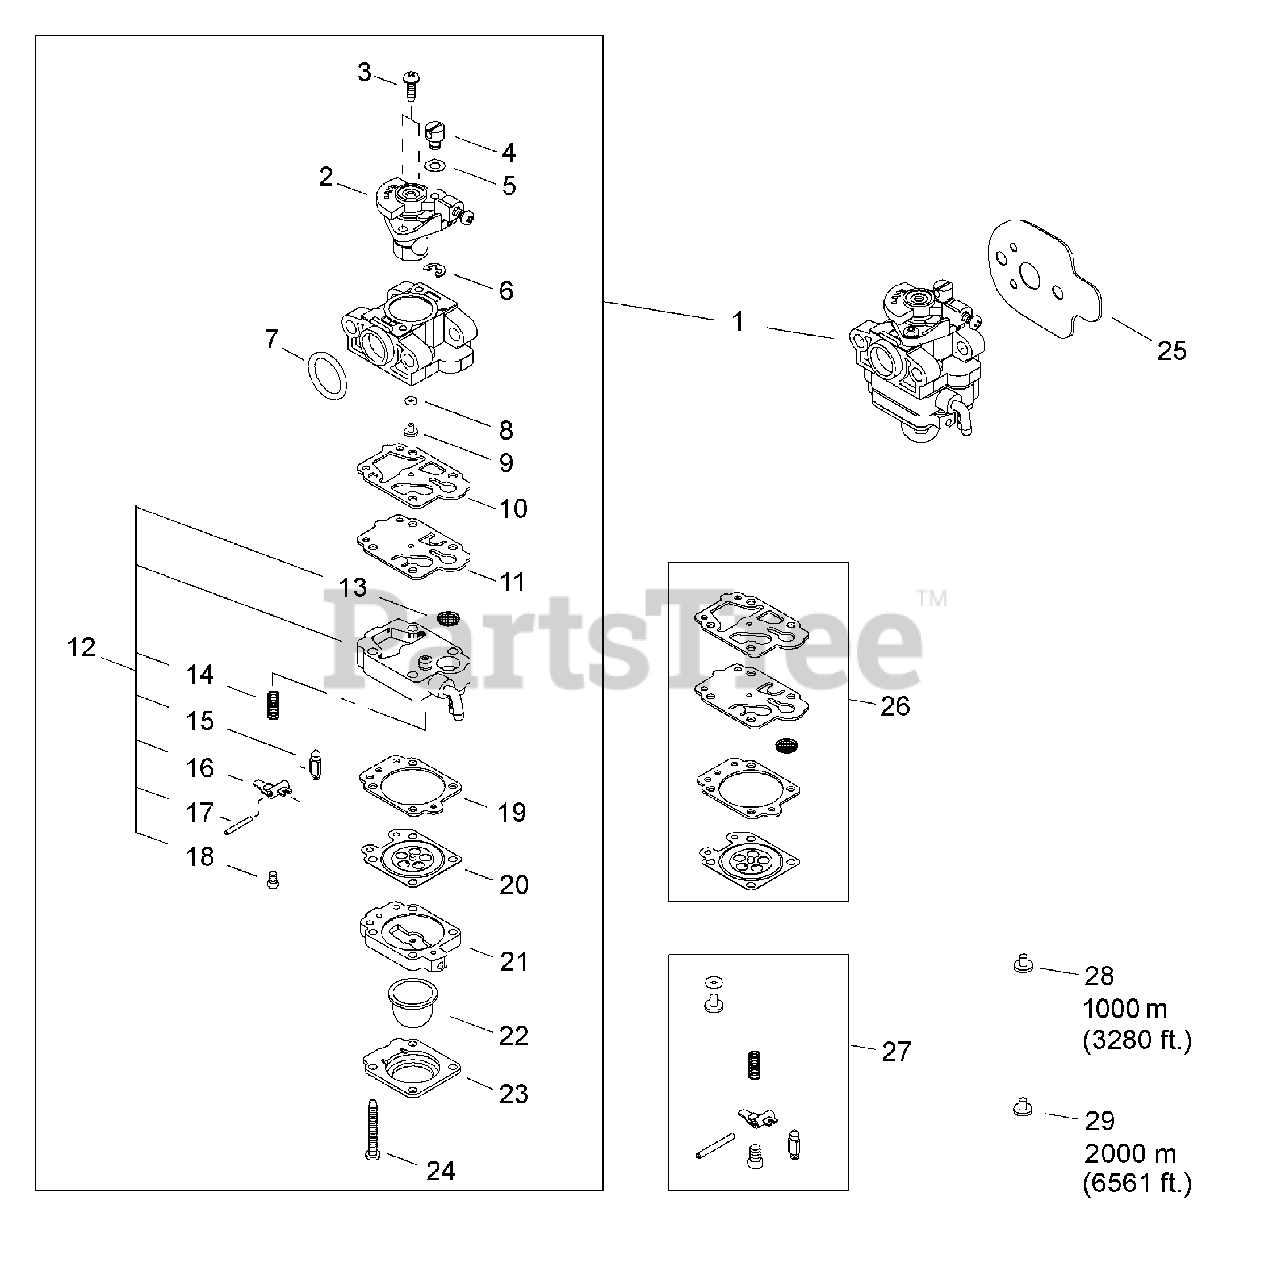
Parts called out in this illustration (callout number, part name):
1	CARBURETOR
2	THROTTLE VALVE ASSY
3	SCREW
4	SWIVEL
5	WASHER
6	RING, RETAINING
7	O-RING - 15
8	O-RING
9	JET, MAIN
10	GASKET, PUMP
11	DIAPHRAGM, PUMP
12	PUMP BODY ASSY
13	STRAINER
14	SPRING, METERING LEVER
15	VALVE, INLET NEEDLE
16	LEVER, METERING
17	PIN, METERING LEVER
18	SCREW, METERING LEVER PIN
19	GASKET, METERING
20	DIAPHRAGM, METERING
21	BASE, PURGE
22	BULB, PURGE
23	RETAINER, PURGE BULB
24	SCREW, PUMP COVER
25	GASKET, INTAKE
26	DIAPHRAGM/GASKET KIT
27	INLET NEEDLE VALVE KIT
28	JET, MAIN - 1000M #40
29	MAIN JET - 2000M #39
